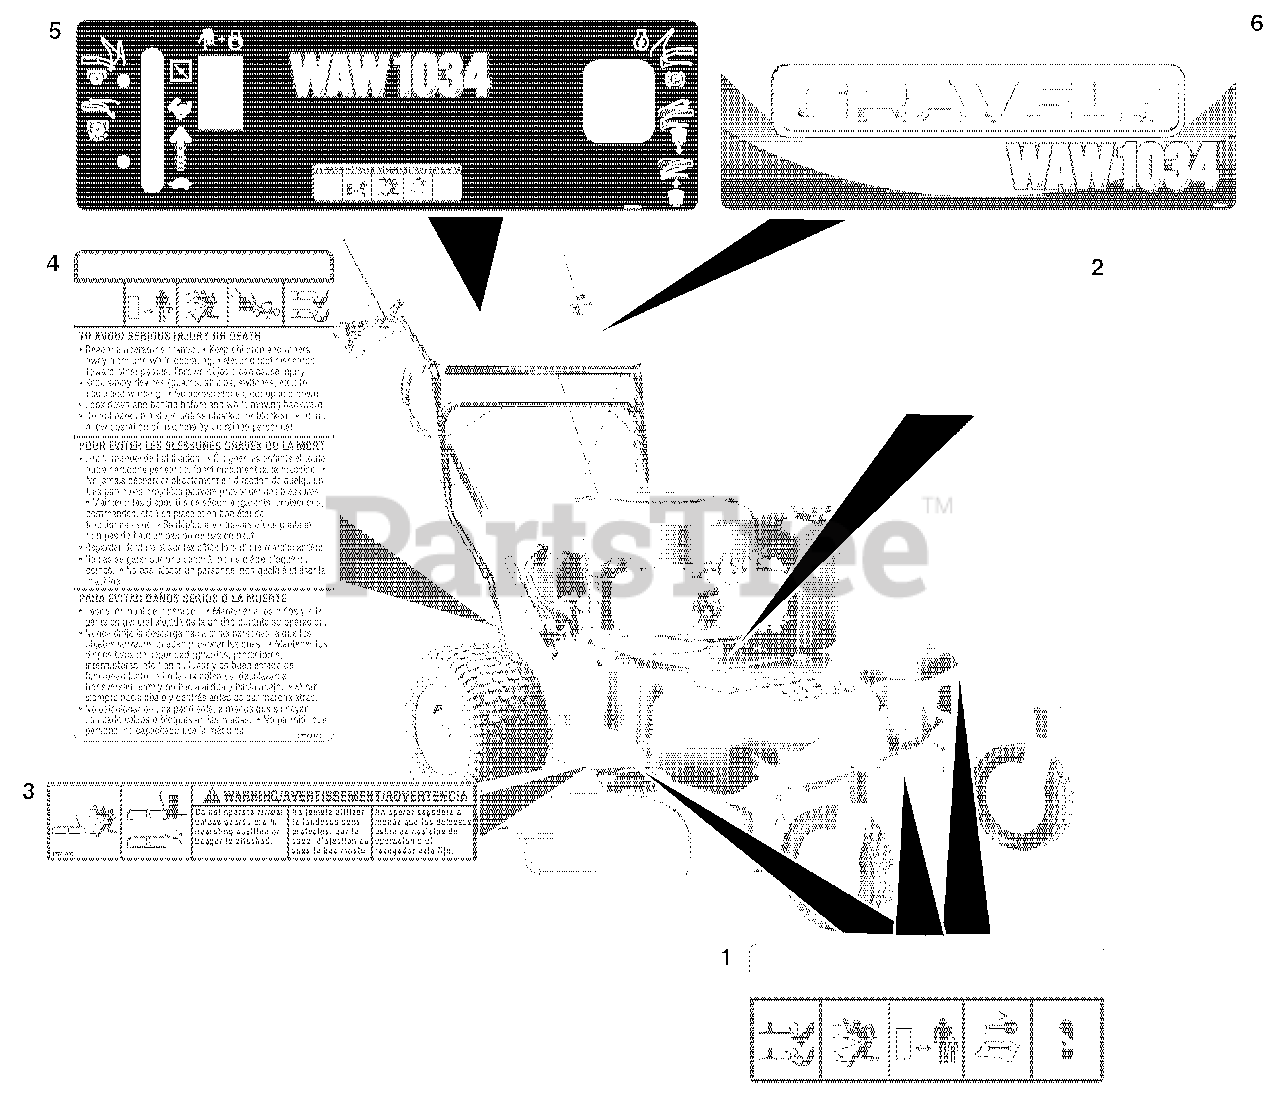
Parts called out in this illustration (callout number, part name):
1	Decal, Mower Pan Head Danger
2	Decal, American Flag
3	Decal, Warning
4	Decal, Bilingual Danger
5	Decal, WAW Operational
6	Decal, WAW 1034 Gravely Dash
